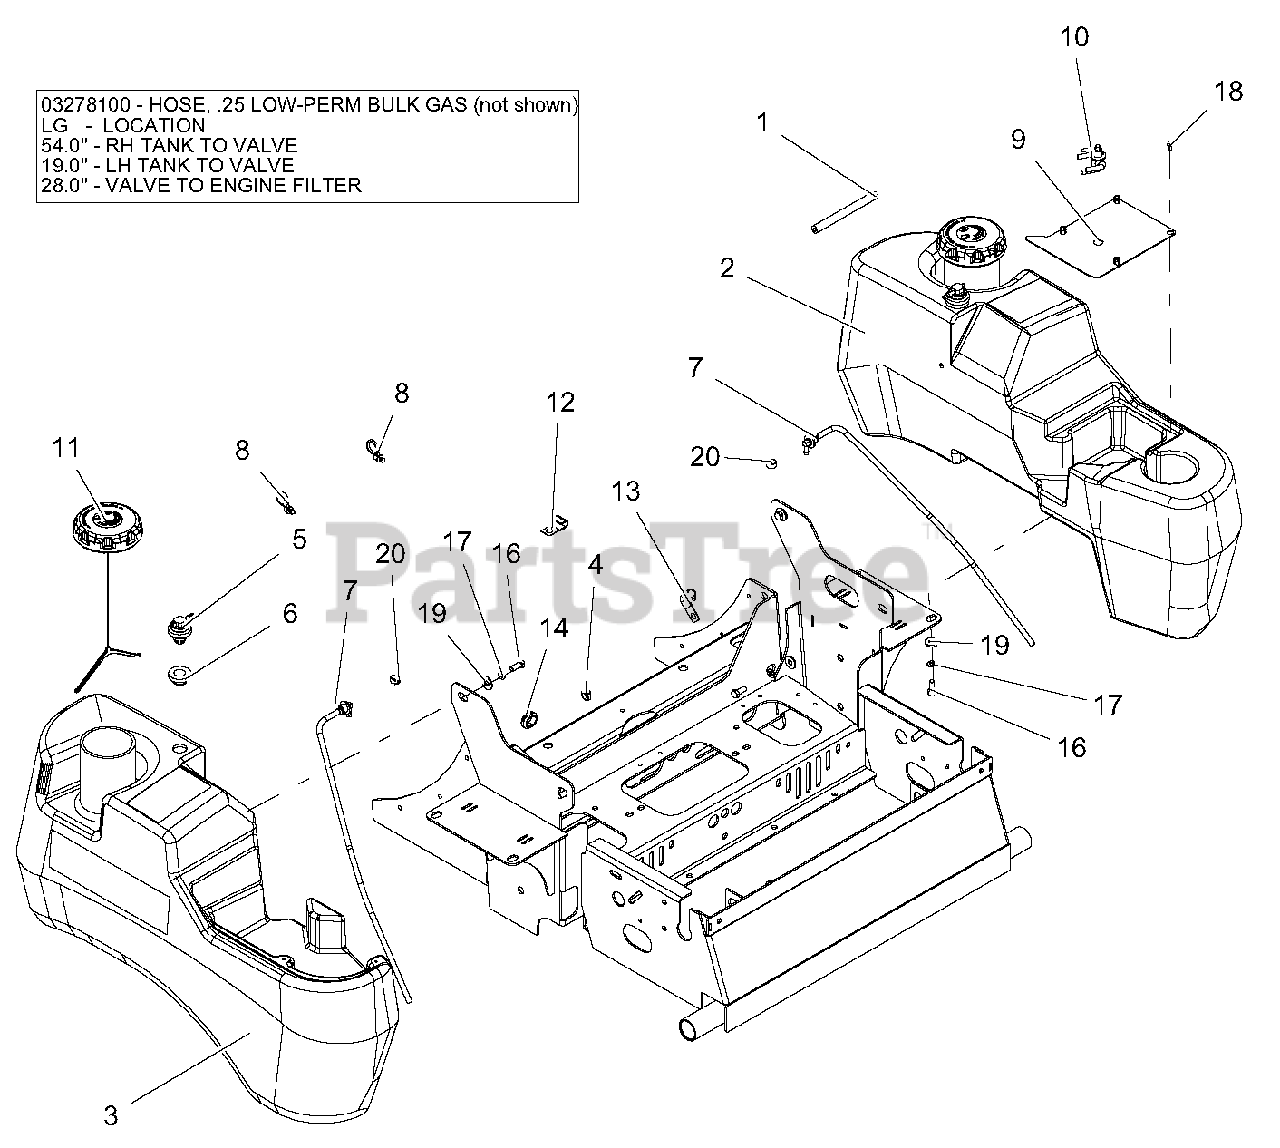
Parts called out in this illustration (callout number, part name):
1	PT400, FUEL LINE ASSEMBLY
2	TANK, LH LARGE GRAVELY FUEL
3	TANK, RH LARGE GRAVELY FUEL
4	CLIP, ROUTING (.50 ID)
5	VALVE, COMBINATION
6	GROMMET, REMOTE VENT NITRILE
7	ASM, LARGE TANK FUEL PICKUP
8	CABLE TIE W/ TREE (.25 HOLE)
9	PLATE, FUEL VALVE MOUNTING-RED
10	VALVE, FUEL
11	CAP, FUEL VENT-IN AUTOLOCK
12	, J-CLAMP
14	GROMMET, RUBBER
16	BLT-HEX .31-18X.75 GR5 YWZC
17	@WSHR-LK .31X.078 REG YWZC
18	SCR-MCH 10-24X.38 HWHSTAINLESS
19	@WSHR-FL-STL.38X.875X.083 YWZC
20	CLAMP, FUEL LINE
